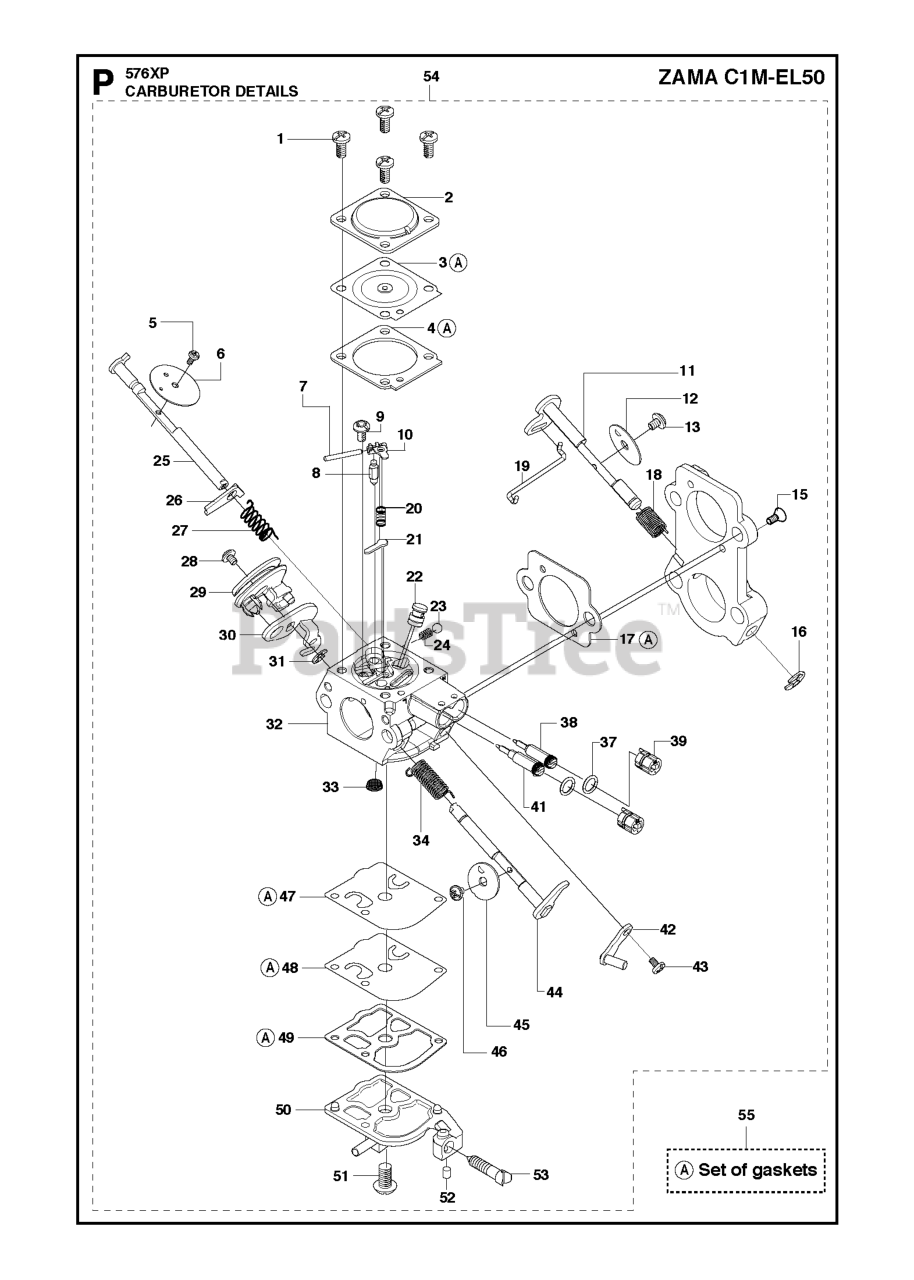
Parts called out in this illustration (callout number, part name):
6	CHOKE FLAP
7	PIN RETAINING SCREW
8	INLET NEEDLE
12	THROTTLE FLAP
25	CHOKE SHAFT
39	LIMITER CAP KIT
47	PUMP DIAPHRAGM
54	CARBURETTOR
55	GASKET SET
